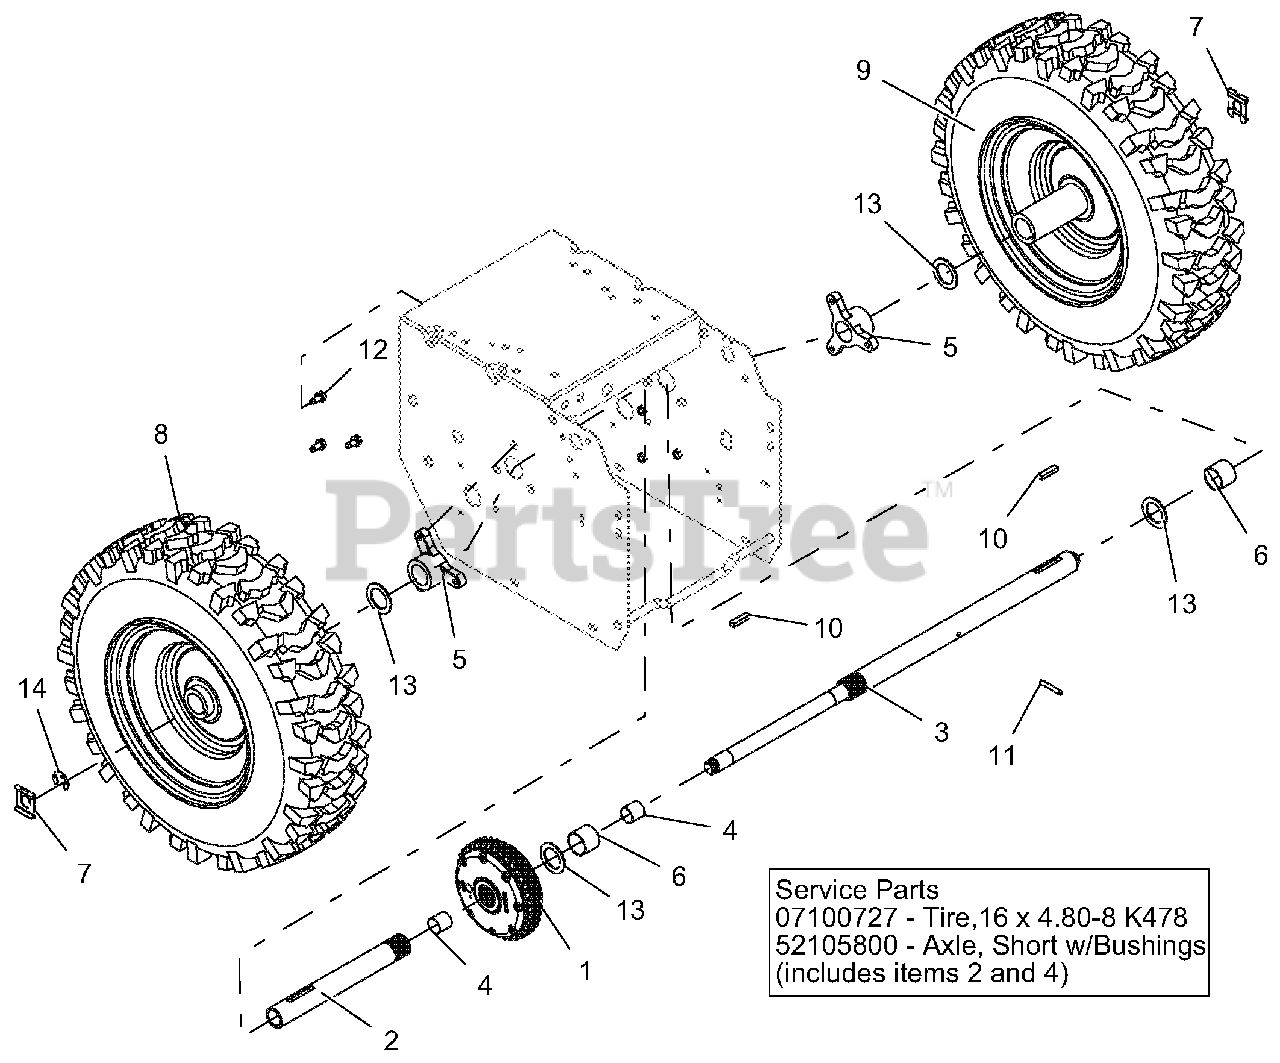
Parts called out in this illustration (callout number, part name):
1	DIFFERENTIAL, AUTOMATIC
2	AXLE, SHORT W/BUSHINGS
3	AXLE, LONG - DIFFERENTIAL
4	BSHG-SLV .706X.764X.75 BRZ
5	BUSHING, AXLE
6	BSHG-SLV, 1.012X1.125X.875
7	CLIP, SNAP .625 DIA
8	TIRE/WHEEL,RH 16X4.8-8 DIFF T2
9	TIRE/WHEEL,LH 16X4.8-8 DIFF T2
10	KEY-RECT .25X.188X1.00
11	PIN-ROLL .188X1.25
12	SCR-TAP .25-20X.50 HWH TR YWZ
13	WSHR-FL-STL 1.010X1.505X.062YZ
14	RG-RTNG-EXT .625X.042
